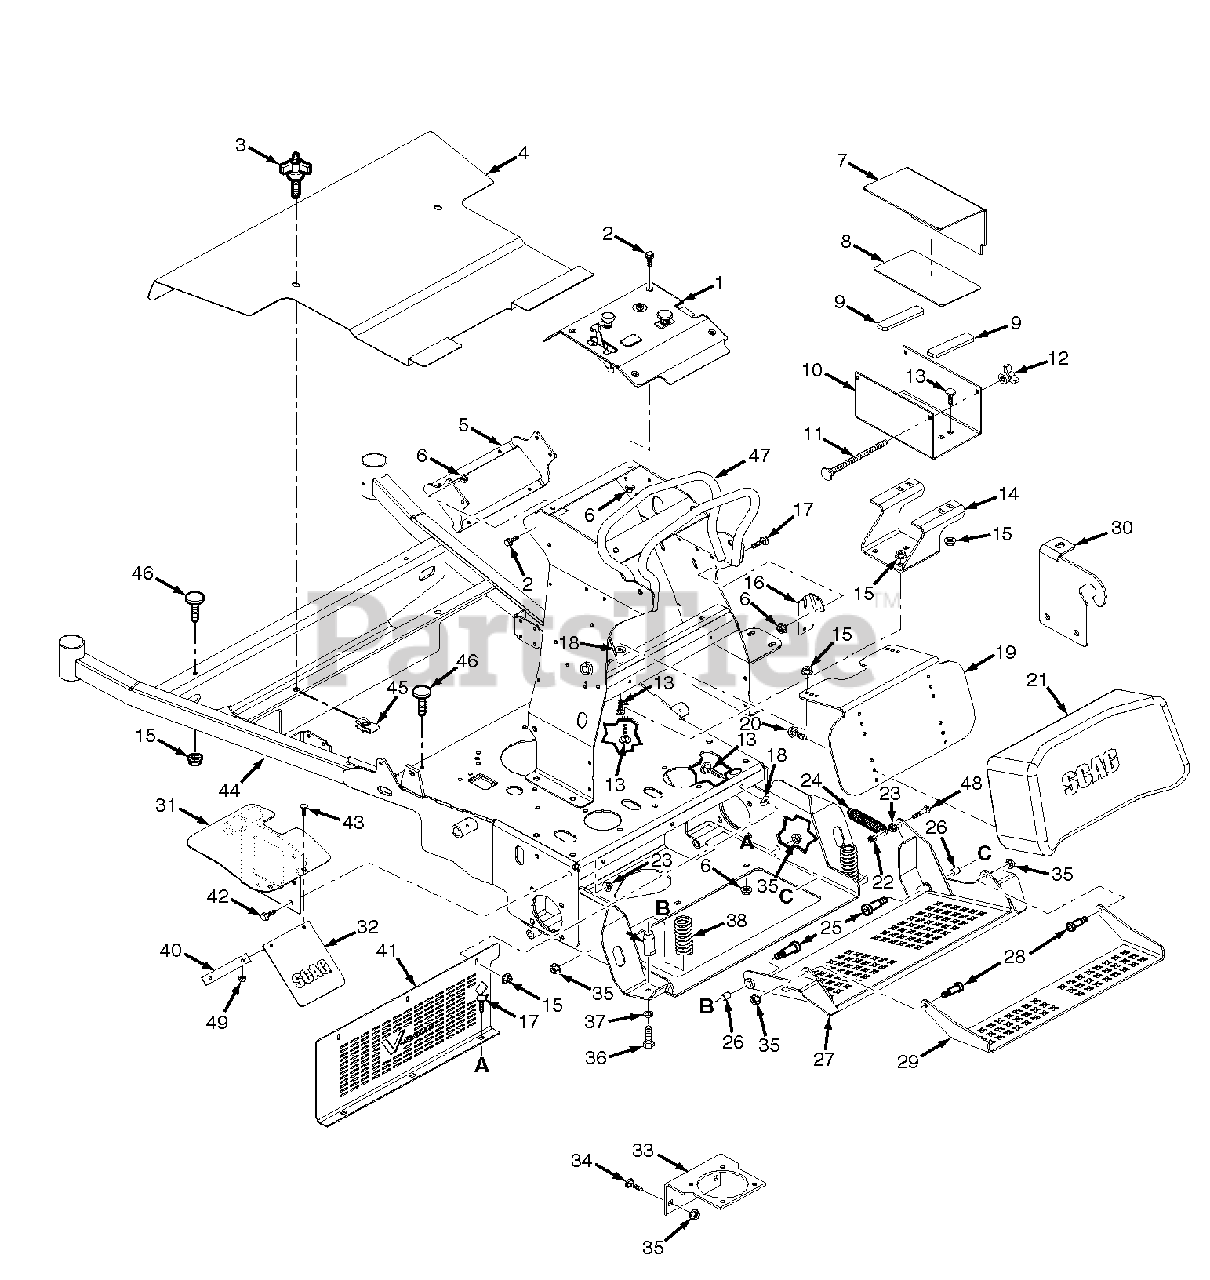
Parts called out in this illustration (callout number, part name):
1	Instrument Panel w/Decal
2	Bolt, Hex Head 1/4-20 x .63
3	Knob w/Stud
4	Belt Cover w/Decals
5	Bracket, Oil Cooler
6	Nut, Serrated Flange 1/4-20
7	Battery Cover
8	Insulation, Battery Cover
9	Pad, Rubber
10	Battery Box
11	Bolt, Carriage 1/4-20 x 6"
12	Wing Nut, 1/4-20
13	Bolt, Carriage 5/16-18 x 3/4"
14	Bracket, Battery Support
15	Nut, Serrated Flange 5/16-18
16	Bracket, Neutral Switch
17	Bolt, Carriage 1/4-20 x 3/4"
18	Nut, Push On 5/16"
19	Bracket, Knee Pad
20	Bolt, Hex Head 1/4-20 x 3/4"
21	Knee Pad
22	Nut, Elastic Stop 3/8-16
23	Nut, 3/8-16 Serrated Flange
24	Spring
25	Bolt, Shoulder 1/2 x 1"
26	Bearing
27	Footplate Assembly
28	Bolt, Shoulder 3/8 x 1/4"
29	Footplate Extension
30	Brake Shaft Support
31	Fender Weldment
32	Mudflap
33	Bracket, Oil Filter Base
34	Bolt, Hex Head 3/8-16 x 1"
35	Nut, Serrated Flange 3/8-16
36	Bolt, Hex Head 3/8-16 x 3/4"
37	Lockwasher, 3/8"
38	Spring, Foot Platform
39	Pin, Spring Mount
40	Strap, Mudflap
41	Guard, Foot
42	Bolt, Hex Head 3/8-16 x 1"
43	Bolt, Carriage 5/16-18 x 3/4"
44	Mainframe Assembly w/Decals
45	U-Nut, 3/8-16
46	Bumper, Rubber
47	Handle Weldment
48	Bolt, Hex Head 3/8-16 x 1-1/4" Grade 8
49	Nut, Center Lock 5/16-18
